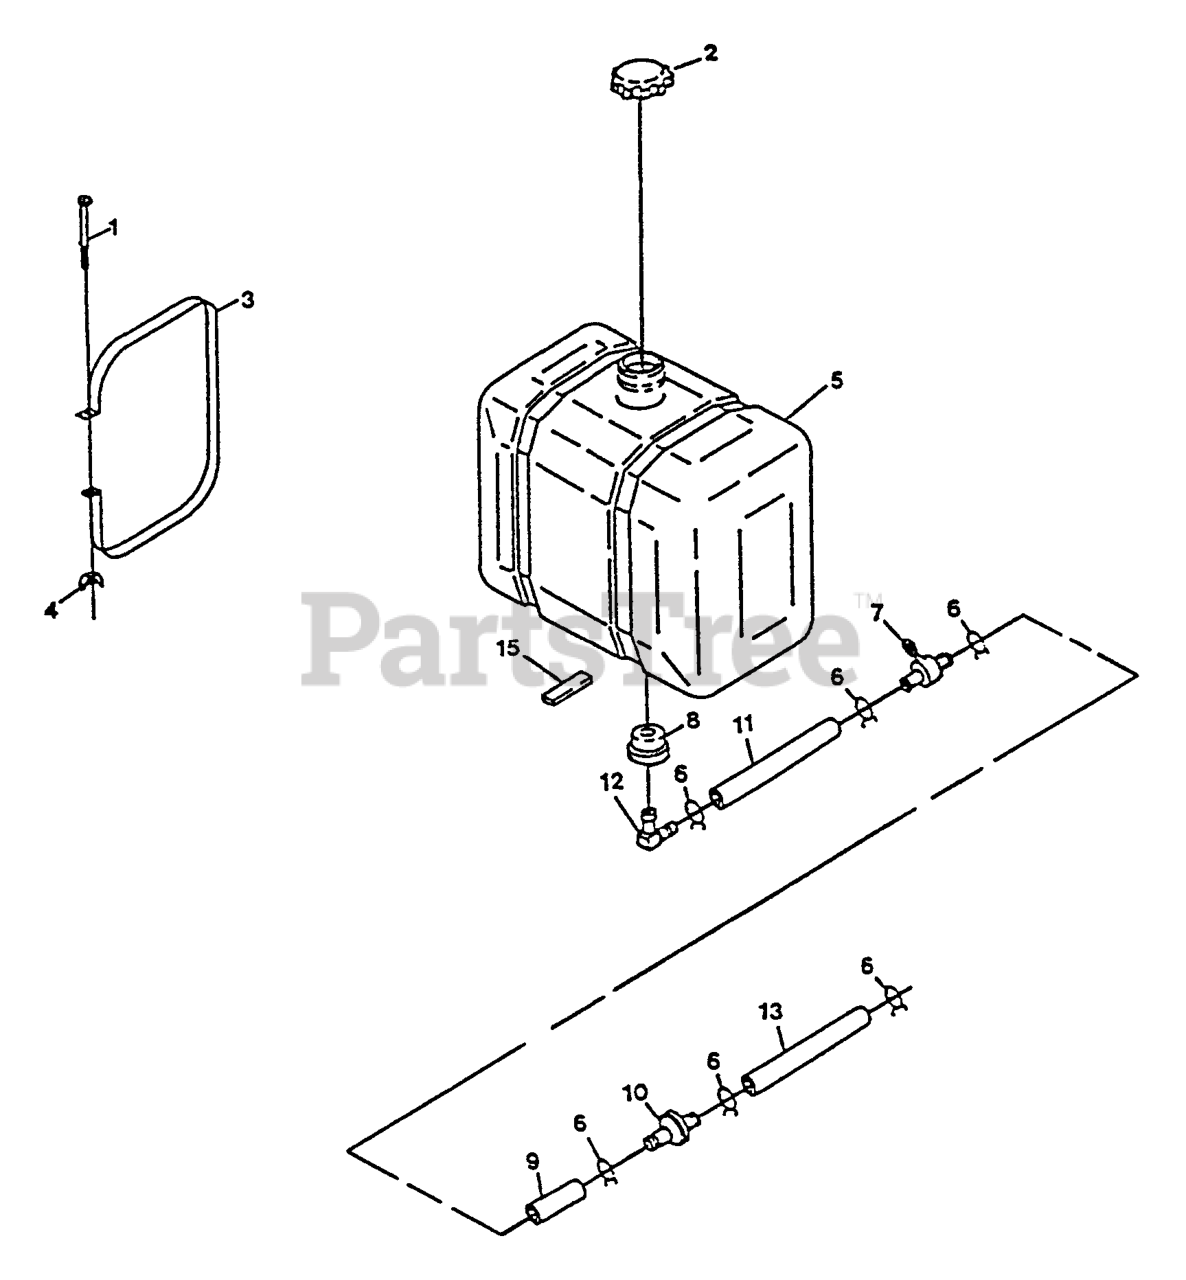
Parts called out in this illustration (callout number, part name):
1	SCRW,MACH CRPH
2	CAP-FUEL
4	WINGNUT
7	VALVE-FUEL
9	HOSE-LINE, FUEL
12	ELBOW-TANK, FUEL
14	PAD,PLASTIC TANK
